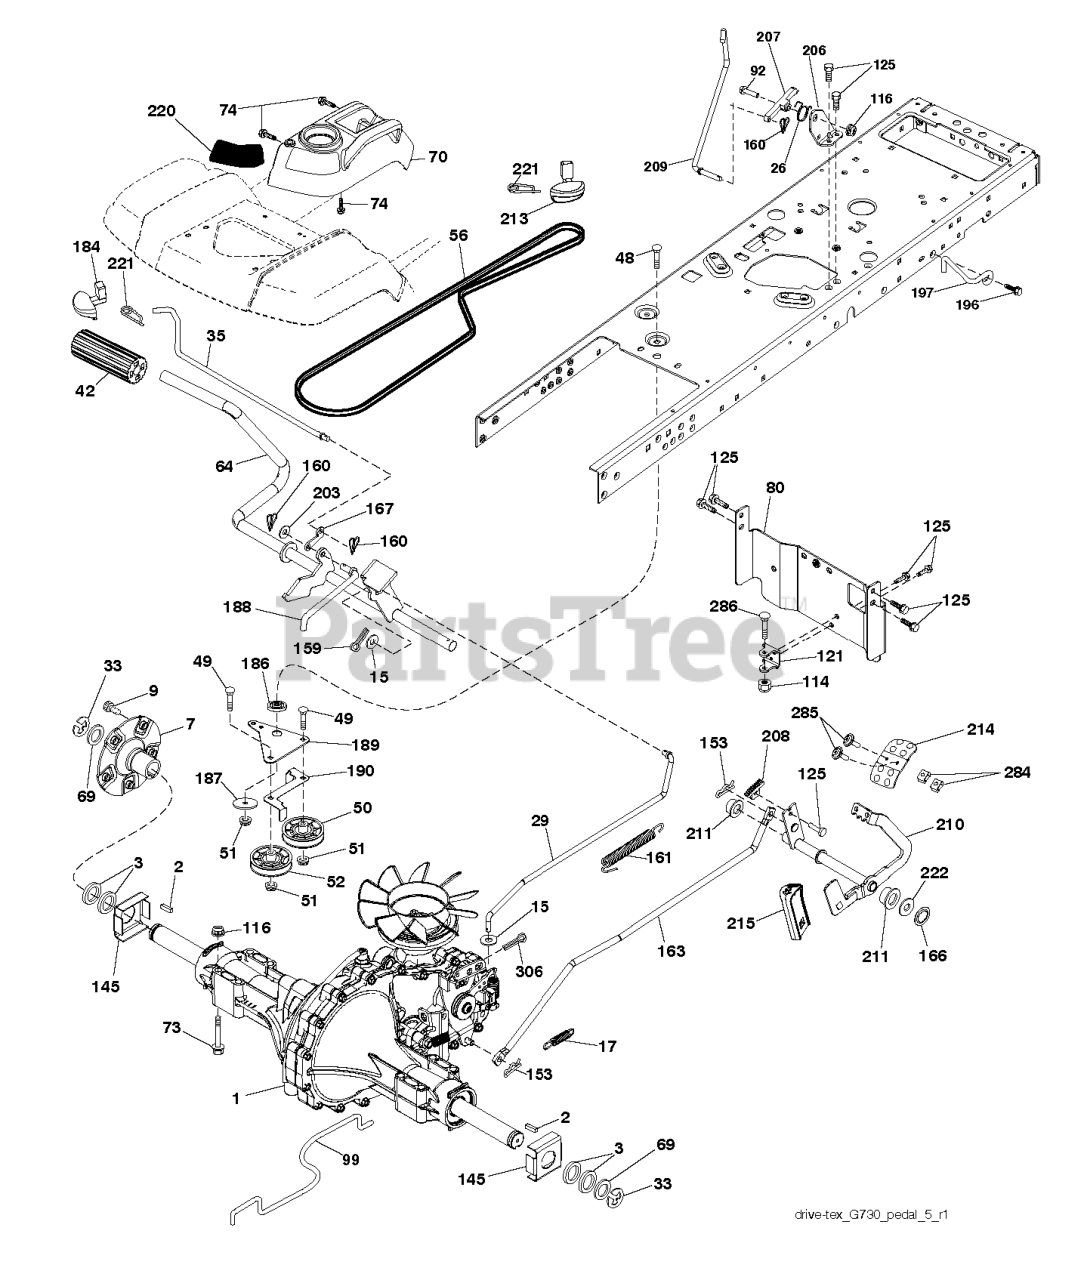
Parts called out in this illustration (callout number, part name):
2	KEY 1/4 X 2.5
7	HUB.ASM.WHEEL.REAR.23"TEX
15	WASHER
17	SPRING.BRAKE.HG3000/3500
26	SPRING.RETURN.CRUISE
33	E RING HYT
35	ROD.BRAKE.PARKING.GT.H
42	PEDAL COVER T
48	BOLT.3/8-16X1.50
50	IDLER.FLAT.910.OFFSET
51	NUT LOCK FLG 3/8-16 UNC
52	IDLER.V-GROOVE.910.OFFSET
56	V-BELT.GROUND.DRIVE.
64	SHAFT.ASM.PEDAL.BRK.CNTR
70	RP CONSOLE.ASM.PCH.W/TB
73	BOLT HEX FLGHD 5/16-18X3 GR. 5
74	SCREW.HI-LO.CONSOLE
80	STRAP.TORQUE.YT.G700
92	BOLT
99	SPRING.BYPASS.YT.G700
114	NUT.71038.31-18.HEX.NYLOCK
116	NUT LOCK HEX FLANGE 5/16-18
121	BRACKET STRAP TORQUE
125	SCREW
145	WASHER.AXLE.FLANGE.HG-3000
153	RETAINER M
159	COTTER PIN
160	RETAINER CLIP
161	SPRING, RETURN LT
163	ROD PEDAL CONTROL
166	NUT.PUSH.625
167	LATCH.BRAKE.SPRING
184	HANDLE.PARKG.BRK.HUSQ X667
186	SPACER.RETAINER
187	WASHER 12/32X2X10GA
188	RP.LINK.CLUTCH.GROUND.DRIVE
189	BELLCRANK.GROUND.DRIVE.TRAPPED
190	KEEPER BELLCRANK ROUND DRIVE
196	SCREW 3/8-16X1
197	BRKT.ANIT-ROTATION.CLUTCH
203	WASHER
206	BRKT.MOUNT.LATCH.CRUIS
207	LATCH.CONTROL.CRUISE
208	GEAR.SECTOR.CONTROL.CR
209	ROD.CONTROL.CRUISE.GT.
210	ROCKER.ASM.PEDAL.CONTR
211	BEARING.NYLON
213	KNOB.CONTROL.CRUSIE.HU
214	PEDAL.FORWARD.HUSQVARNA.DEALER
215	PEDAL.REVERSE.TEX.GT.4
220	REFLECTOR.RH.TEX GT
221	RETAINER.SPRING.CLIP.H
222	WASHER 21/32 X 1-1/4 X 10 GA.
284	NUT.U-CHNL.1/4-20.550DP.350PNL
285	SCREW.PHD.1/4-20.BOX DRVE
286	BOLT.5/16-18X2.5
306	PIN COTTER
